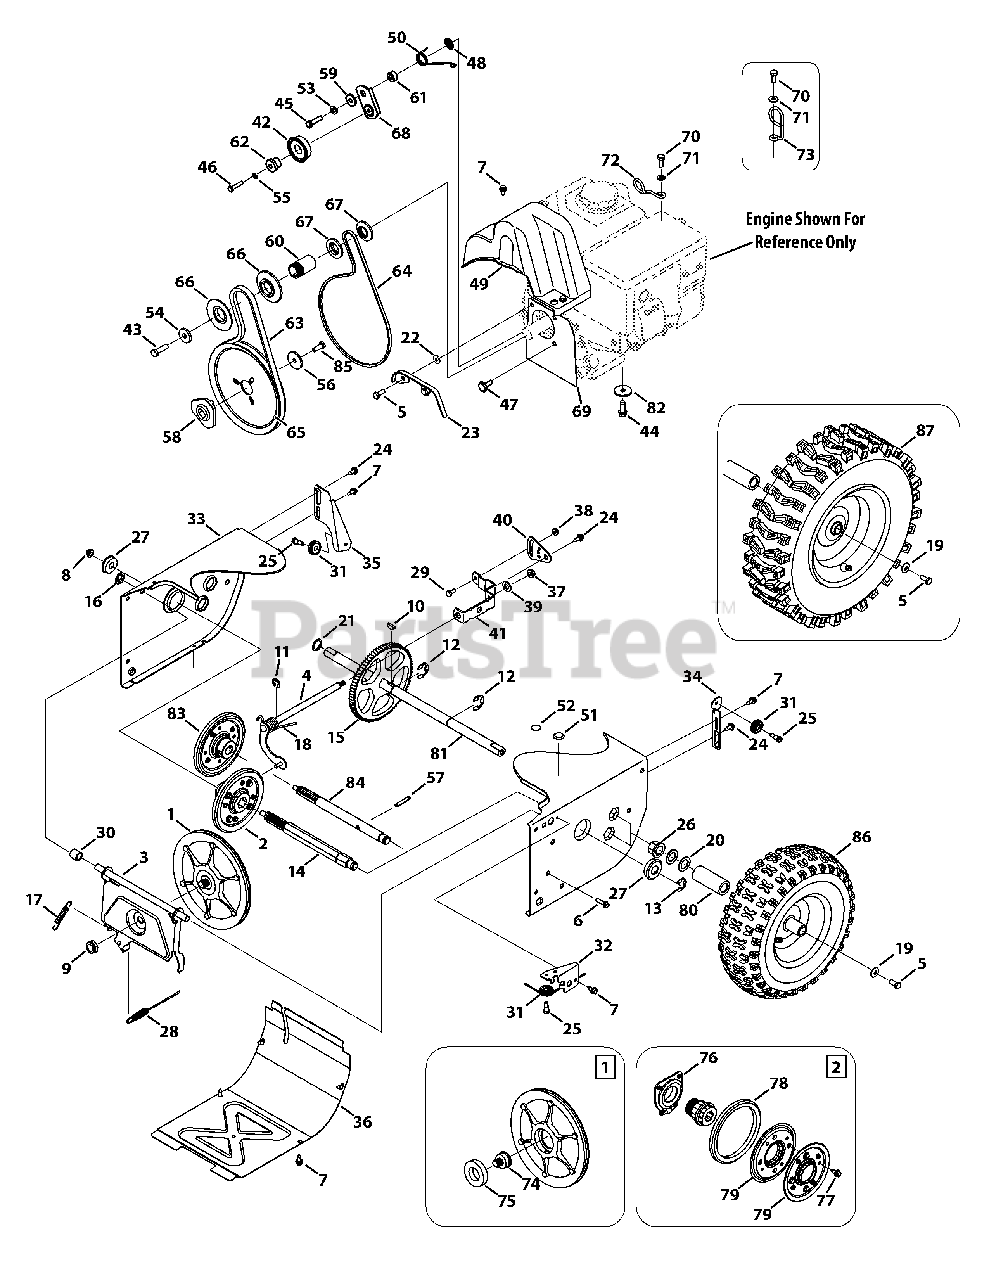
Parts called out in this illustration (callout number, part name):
1	Disc Assembly, Friction Wheel
2	Friction Wheel Assembly, 5.5 OD
4	Rod Shift Assembly
5	Hex Head Screw, 5/16-24 x .750
6	Taptite Screw, 1/4-20 x 1.000
7	Taptite Screw, 1/4-20 x .625
8	Flange Lock Nut, 3/8-16
9	Flange Nut, 5/8-18
10	Hi-pro Key, 3/16 x 3/4 Dia.
11	E-Ring
12	Retaining E-Ring, .875 Dia.
13	E-Ring, .750 Dia.
14	Hex Shaft, 7-Tooth
15	Gear, 80-Tooth
16	Speed Nut, .500
17	Extension Spring
18	Torsion Spring, .750 x .968
19	Bell Washer, .340 x .872 x .060
20	Flat Washer, .793 x 1.24 x .060
21	Flat Washer, .75 x 1.00 x .060
22	Washer, Flat, .385 x .62 x .063
23	Belt Cover
24	Shoulder Screw, .368 x .113, 1/4-20
25	Shoulder Screw, 1/4-28, .340 x .355
26	Hex Flange Bearing
27	Ball Bearing, 17 x 40 x 12
28	Wheel Clutch Cable, 44.95"
29	Hex Head Screw, 1/4-20 x .620
30	Spacer, .508 ID x .75 OD x .68
31	Cable Roller
32	Auger Cable Front Guide Bracket
33	Frame - Red
33	Frame - Black
33	Frame - Green
33	Frame - Orange
34	Auger Cable Guide Bracket
35	Drive Cable Guide Bracket
36	Frame Cover - Red
36	Frame Cover - Black
36	Frame Cover- Green
36	Frame Cover - Orange
37	Flange Lock Nut, 5/16-18
38	Flange Lock Nut, 1/4-20
39	Washer, Flat, .469 x .875 x .105
40	Speed Selector Pivot Bracket
41	Speed Selector Shift Bracket
42	Idler Pulley Assembly
43	Hex Screw, 3/8-24 x 1.25
44	Sems Screw, 3/8-16 x 1.00
45	Hex Screw, 5/16-24 x 1.25
46	Hex Screw, 1/4-20 x 1.25
47	Shoulder Screw, 5/16-24 x .5
48	Push-on Nut, .25 Dia.
49	Belt Cover, 4-Way (large block engine)
49	Belt Cover, 4-Way
49	Belt Cover, Standard
50	Torsion Spring, .850 ID x .333
51	Plug, 3/8 ID
52	Plug, 1/2 ID
53	Lock Washer, 5/16
54	Flat Washer, .406 x 1.25 x .157
55	Washer, Lock, 1/4
56	Flat Washer, .34 x 1.50 x .150
57	Pin, Spirol, 2.5"
58	Adapter Pulley, .75 Dia.
59	Shoulder Spacer, .3175 x .5 x .0975
60	Spacer, .875 ID x 1.185 OD
61	Spacer, .340 x .750 x .330
62	Shoulder Space, .260 x .785 x .538
63	Auger Drive Belt, 4-Way (large block engine)
63	Auger Drive Belt, Standard
64	Wheel Drive Belt, 4-Way (large block engine)
64	Wheel Drive Belt, Standard
65	Auger Drive Pulley, 8.1 x .5
66	Pulley Half, 2.600 OD
67	Pulley Half, 3/8 x 1.716 OD
68	Wheel Drive Idler Bracket
69	Cover Plate, 4-Way lrg. block
69	Cover Plate, Standard
70	Hex Head Screw, 1.25 x 20
71	Washer, Flat, .330 x .630 x .0635
72	Cable Guide
73	Cable Guide
74	Friction Disc Bearing Pin
75	Ball Bearing, 30 x 55 x 13
76	Bearing Assembly
77	Screw, 1/4-14 x .625
78	Friction Wheel Rubber
79	Friction Wheel Plate
80	Spacer, 1.25 x .75 x 3.0
81	Axle, .75 x 22
82	Washer, Flat, .38 x 1.38 x .125
83	Friction Wheel Ass’y, Single-Speed
84	Shaft, Single-Speed
85	Hex Cap Screw, 5/16-24 x .875
86	Snow Hog Wheel, 13 x 4 x 6
86	Snow Hog Wheel, 15 x 5 x 6
86	Snow Hog Wheel, 15 x 4.8
87	X-Trac Wheel, 16 x 4.8 x 8, LH
87	X-Trac Wheel, 16 x 4.8 x 8, RH
87	X-Trac Wheel, 16 x 6.5 x 8, RH
87	X-Trac Wheel, 16 x 6.5 x 8, LH
